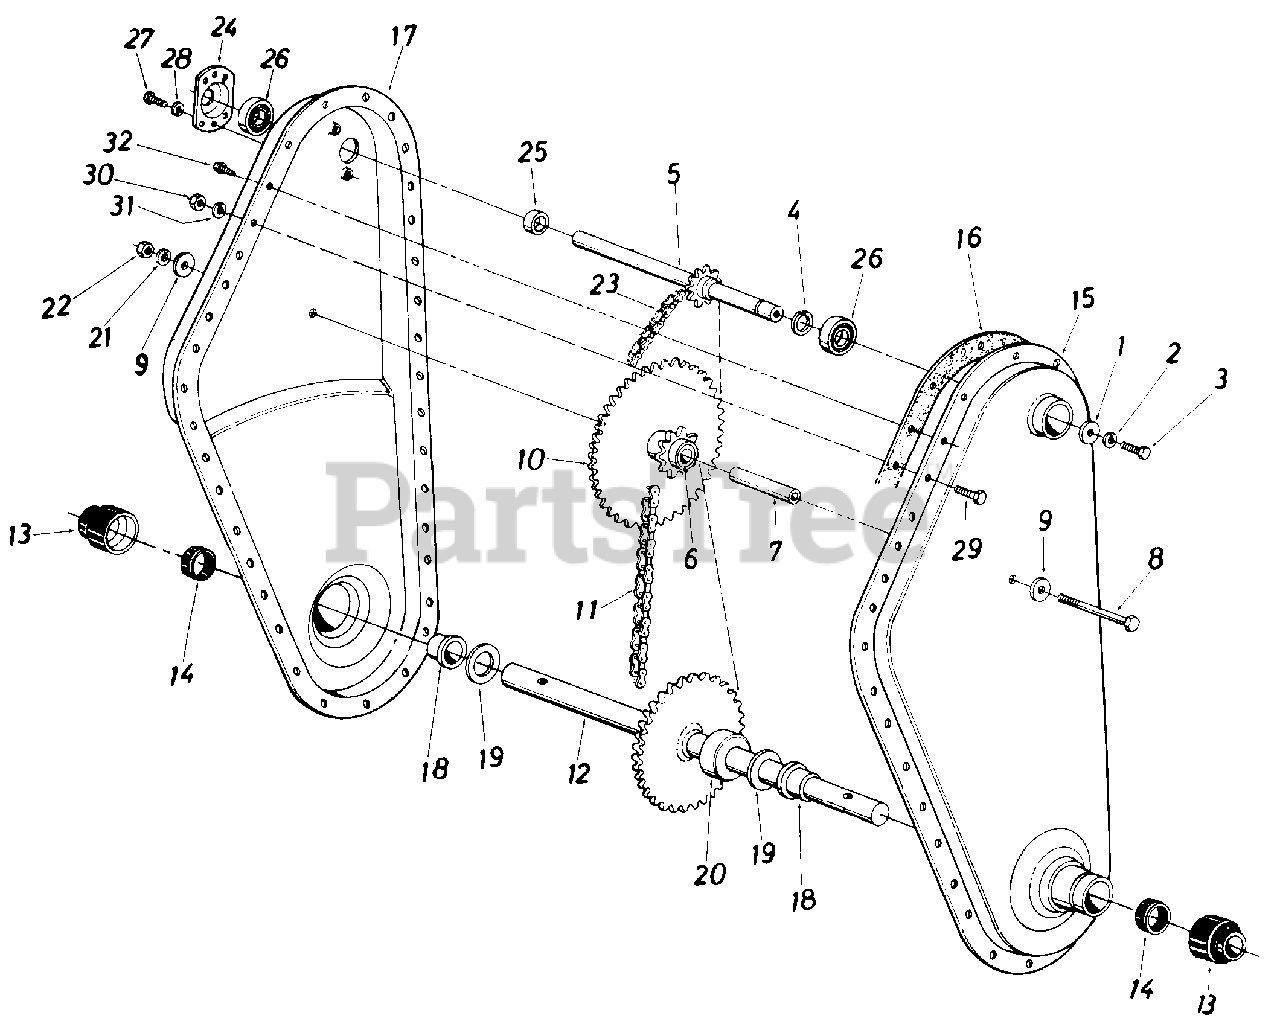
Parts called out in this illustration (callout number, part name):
1	Fl-Wash. 1/4" I.D. x .93" O.D. x . 1 20
2	L-Wash. 1/4" I.D.
3	Hex Bolt 1/4-28 x .62" Lg. w/Patc h
4	External Snap Ring 5/8" Dia.
5	Input Shaft Ass'y.
6	Bearing 5/8" I.D. x 3/4" O.D. x 1.860" Lg.
7	Sprocket Hub Tu bi ng 3/8" I.D. x 5/8" O.D. x 1.90
8	Hex Bolt 3/8-24 x 2.75" Lg.
9	Fl-Wash. 3/8" I.D. x 1.25" O.D. x .10
10	Sprocket Ass'y.
11	#50 Chain 5/8" Pitch x 46 Links Endless
12	Tine Shaft Ass'y.
13	Dust Cup
14	Seal Ring Single Lip, Springless
19	Fl-Thrust Wash. 1.0" I.D. x .03 Thk.
20	Step Spacer
21	L-Wash. 3/8" I.D.
22	Hex Nut 3/8-24 Thd.
23	#35 Chain 3/8" Pitch x 52 Links Endless
24	Bearing Housing 1.38" I.D.
25	Spacer
26	Ball Bearing .625" I.D. x 1.38" O.D. x .437
27	Hex Wash. SF-Tap Scr. 1/4-20 x .50" Lg.
28	L-Wash. 1/4" I.D.
29	Hex Bolt 5/16-18 x .75" Lg.
30	Hex Nut 5/16-18 Thd.
31	L-Wash. 5/16" I.D.
32	Hex Wash. SF-Tap Scr. 1/4-20 x .50" Lg.
